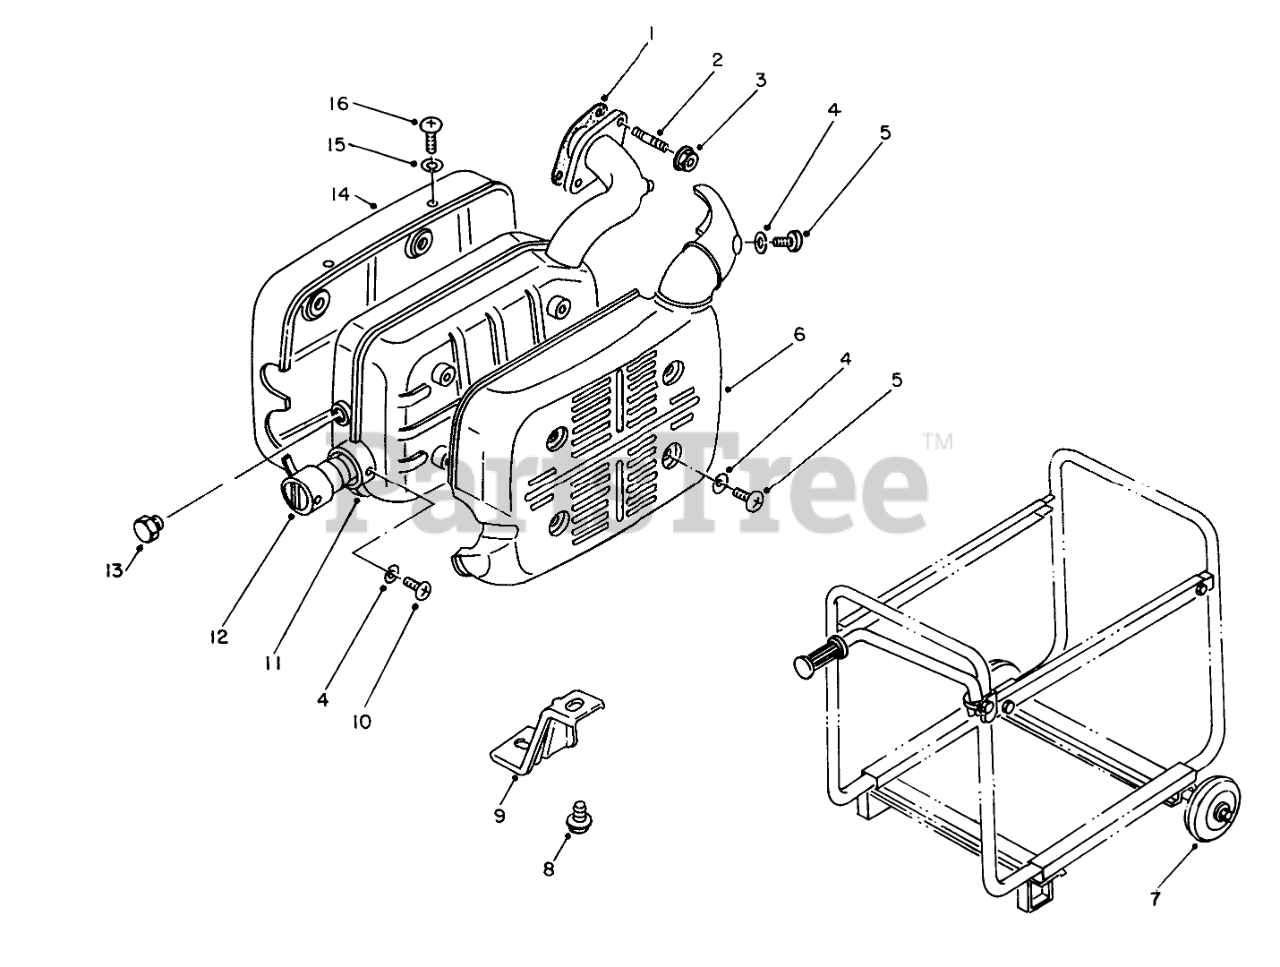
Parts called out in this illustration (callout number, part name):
1	EX GASKET
2	Stud Bolt
4	LOCKWASHER
5	SCREW
6	Cover-Front
7	Wheel Assembly (Optional)
9	Bracket-Muffler
10	Screw
11	MUFFLER ASM
12	Cleanout Tube
13	Drain Plug
14	Cover-Rear
15	Lockwasher
16	Screw
